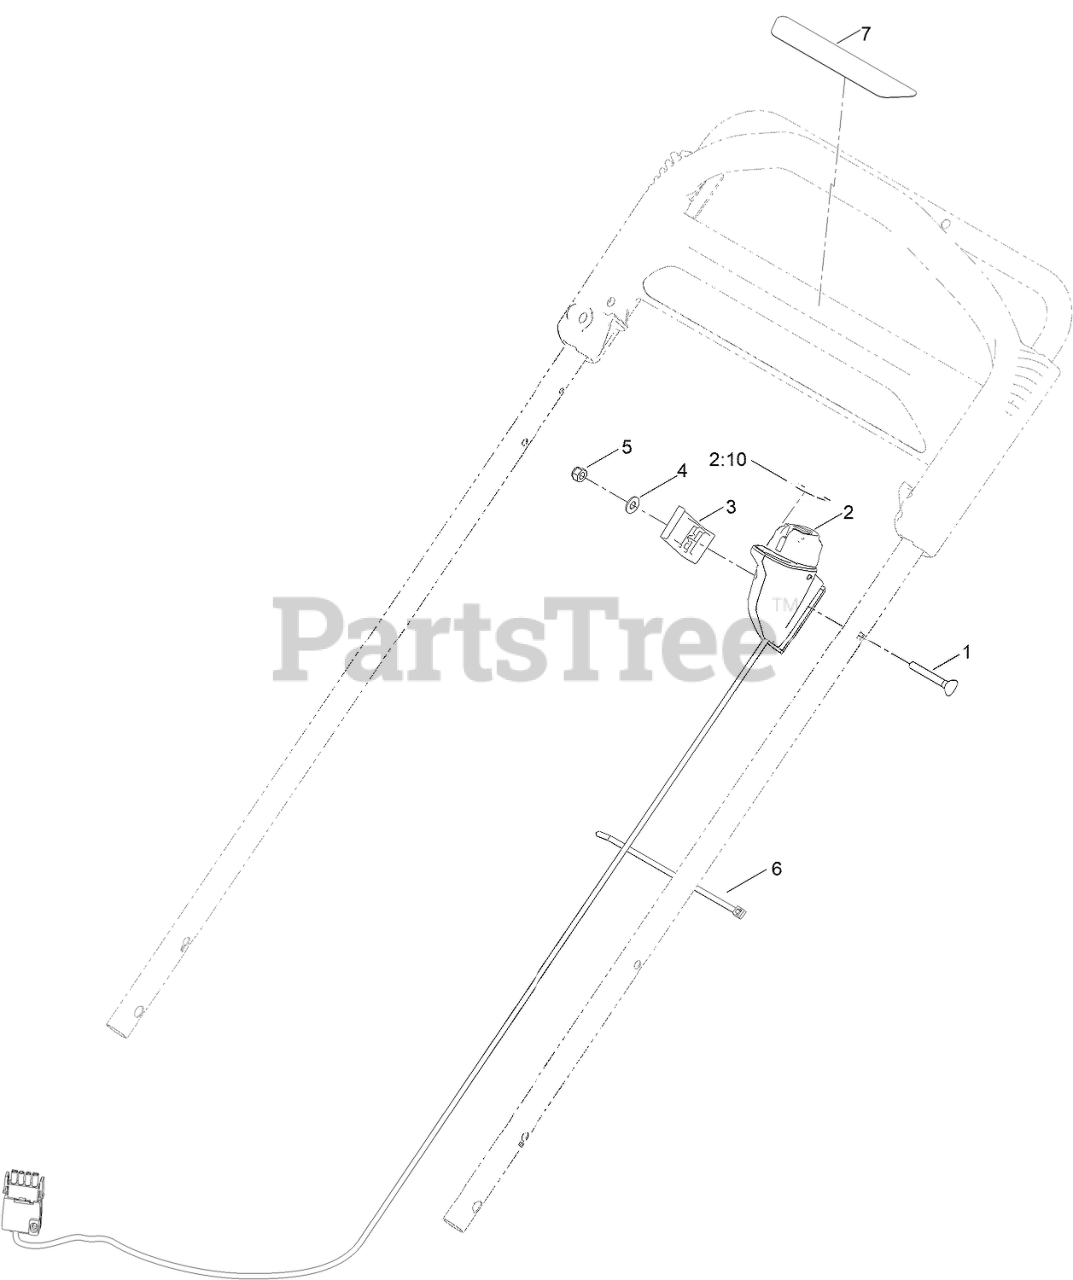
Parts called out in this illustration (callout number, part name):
1	SCREW
2	STARTER SWITCH ASM
2:10	DECAL CONTROL SPEED
3	CLAMP-CABLE
4	WASHER-FLAT
5	NUT-LOCK, NI
6	TIE-CABLE
7	DECAL-CONTROLS (60V, START)
